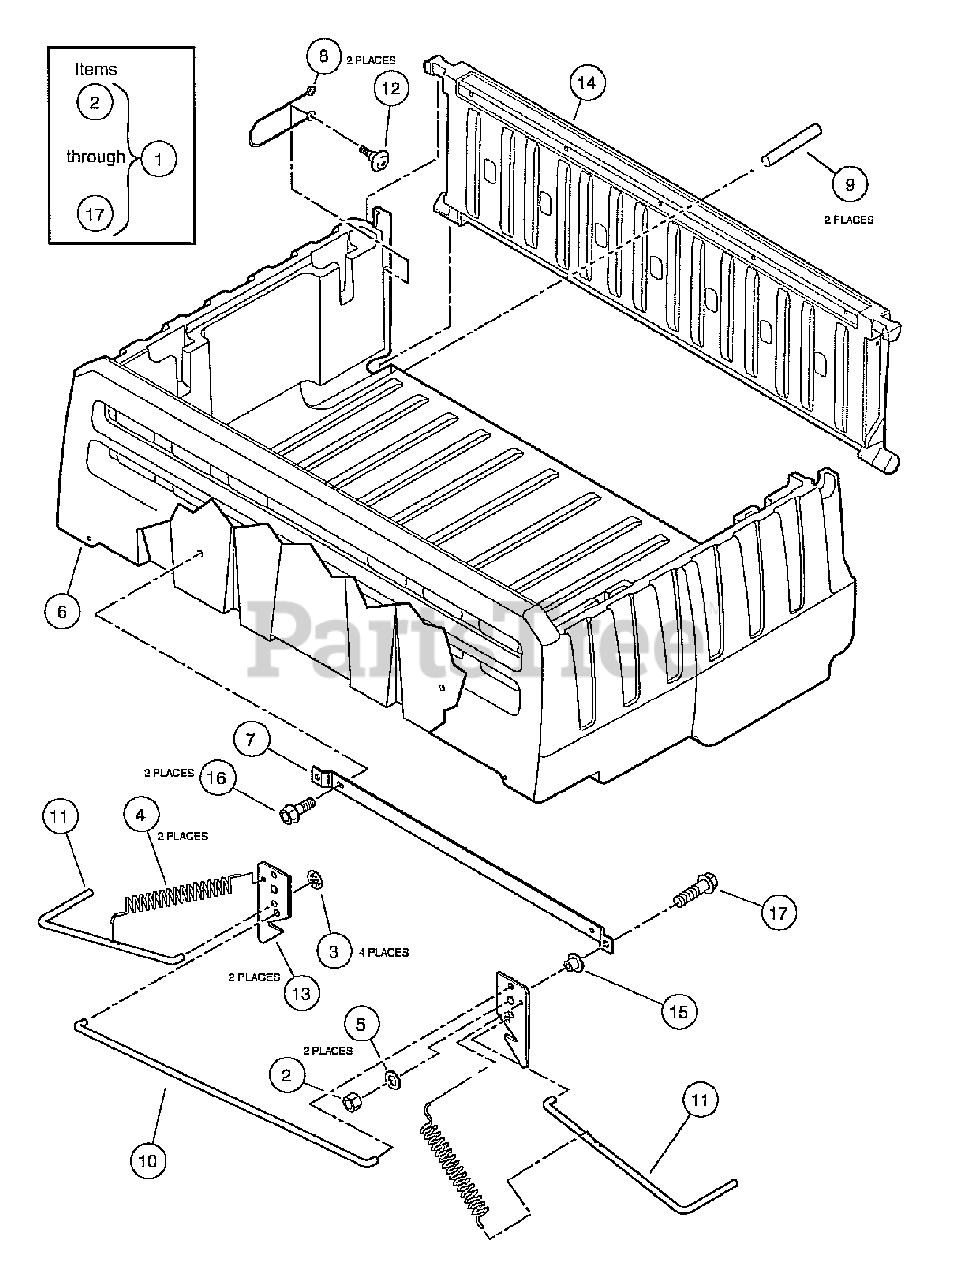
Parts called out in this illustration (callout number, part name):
1	Assembly, Bed
2	Locknut, 3/8-16 Dimpled
3	Pushnut, 3/8
4	Extension, Spring Latch
5	Washer, 3/8 Flat Type A
6	Bed, Cargo
7	Support, Latch Link
10	Rod, Long Link
11	Rod, Bed Lift, Short Bent
13	Catch, Tilt Bed
14	Tailgate
15	Bearing, Bronze, 1/2 x 9/32
16	Screw, 1/4-20 X 1.0 Hex Hd Cap
17	Screw, 3/8-16 X 1.00 Hx Hd Cap
